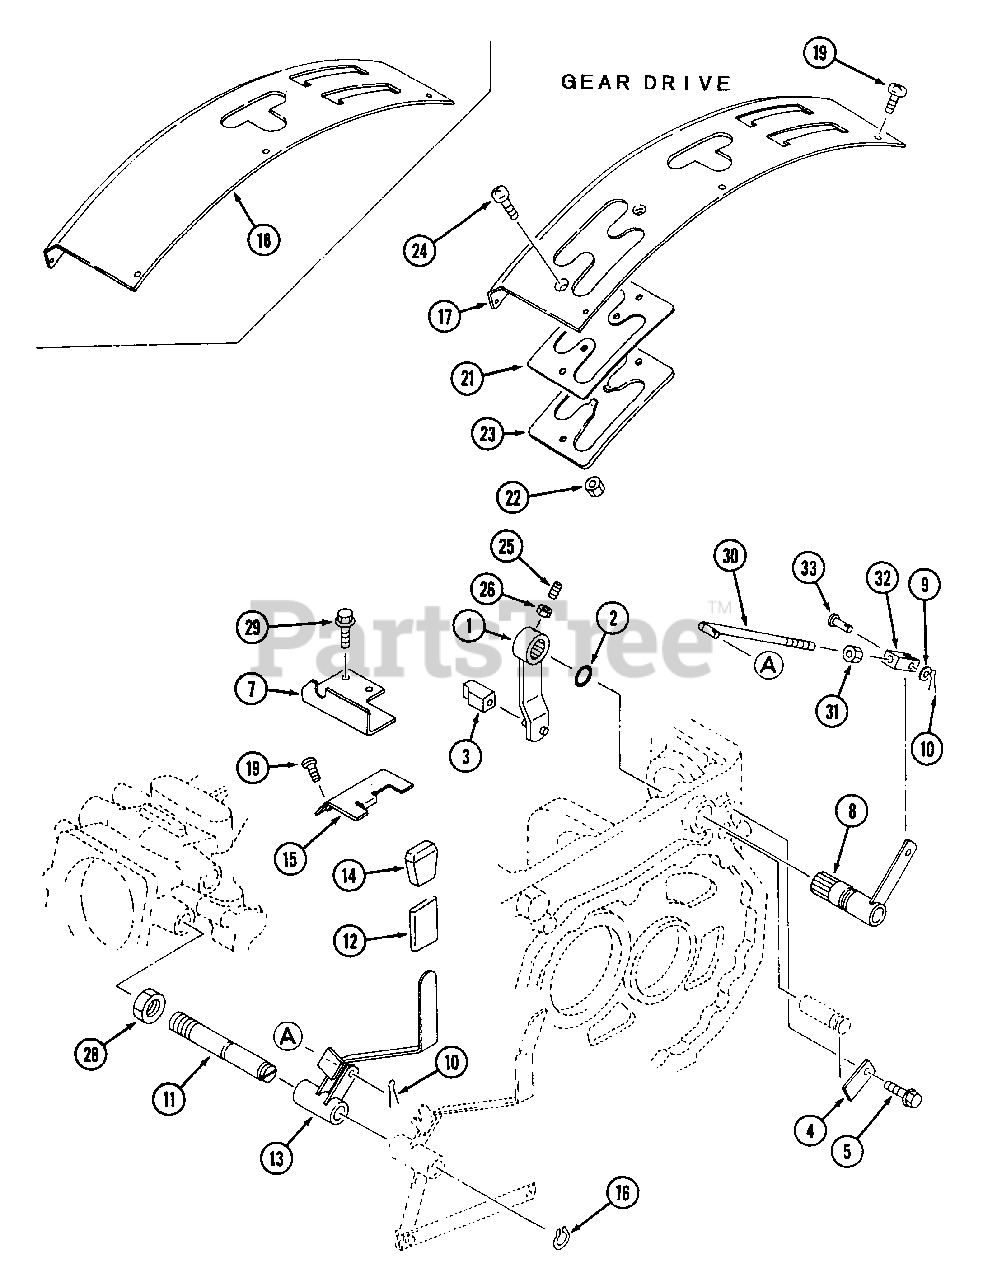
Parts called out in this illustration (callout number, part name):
1	Shifter, R. PTO
10	Pin, Split
11	Shaft, PTO Lever
13	Lever, R. PTO
17	Lever, Guide L.H.
18	Lever, Guide L.H.
21	Guide, Rubber
